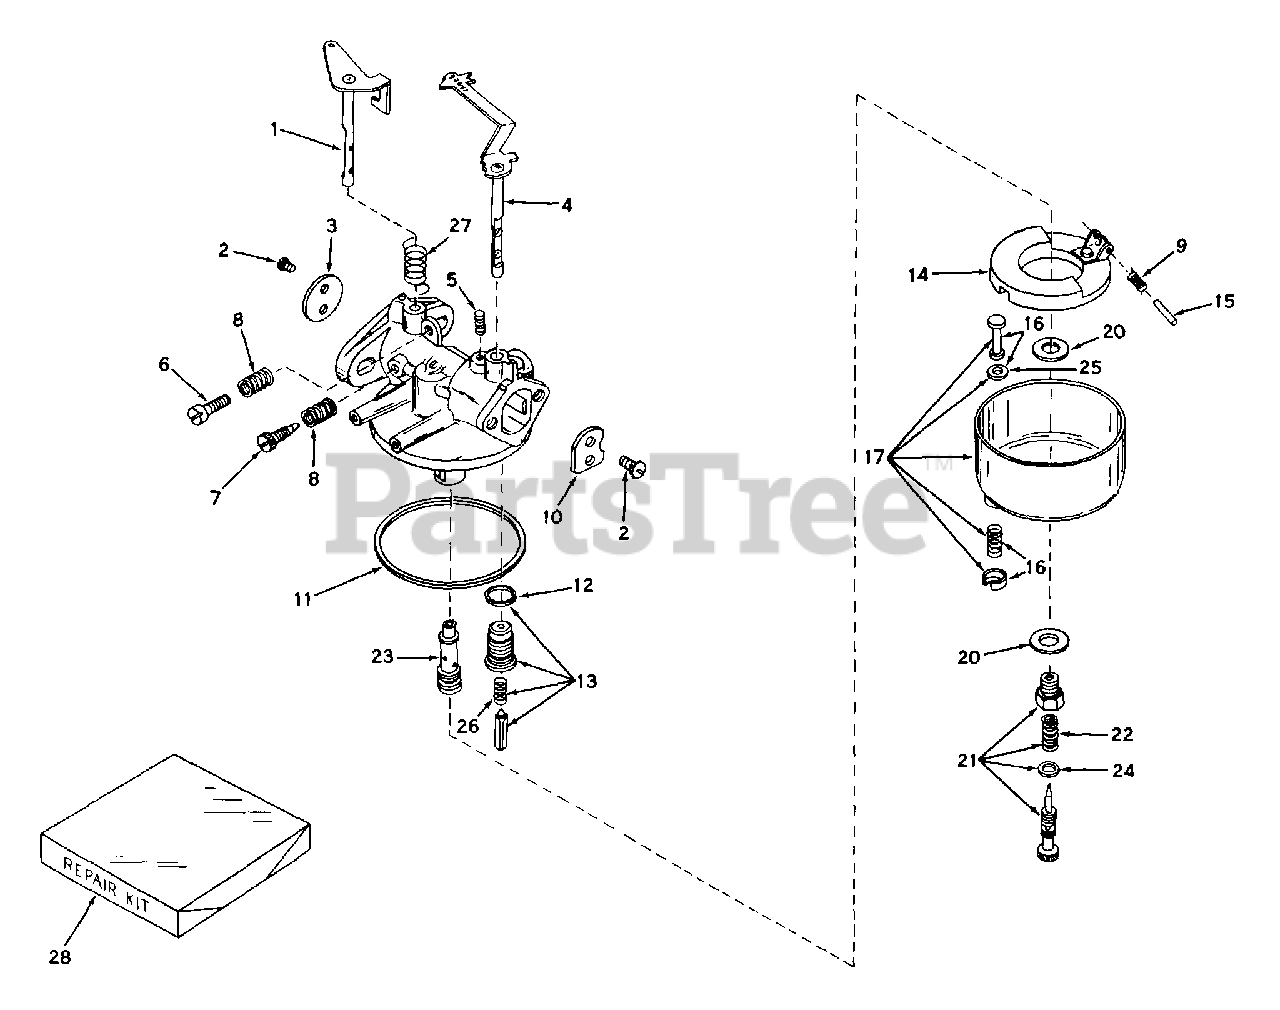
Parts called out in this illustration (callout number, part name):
1	"Shaft & Lever Assy., Throttle
2	Screw, Pan hd. Sems, 4-40 x 3/16
3	Shutter, Throttle
4	Shaft & Lever Assy., Choke
5	Spring, Choke stop
6	Throttle adjusting
7	Needle, Idle adjusting
8	Spring, Adjusting needle
9	Spring, Float shaft
10	Shutter, Choke
11	Gasket, Bowl-to-body
12	Gasket, Valve seat
13	Valve Seat, Gasket & Spring Assy. (.0 55
15	Shaft, Float
16	Drain Assy., Bowl
17	Bowl & Drain Assy.
20	Gasket, Bowl-to-body
21	Needle Assy., Power adjusting (Incl. Nos. 22
22	Spring, Adjusting needle
23	Nozzle, Main
24	"O" Ring
25	Gasket, Drain stem
26	Spring, Float valve
27	Spring, Throttle return
28	Repair Kit
